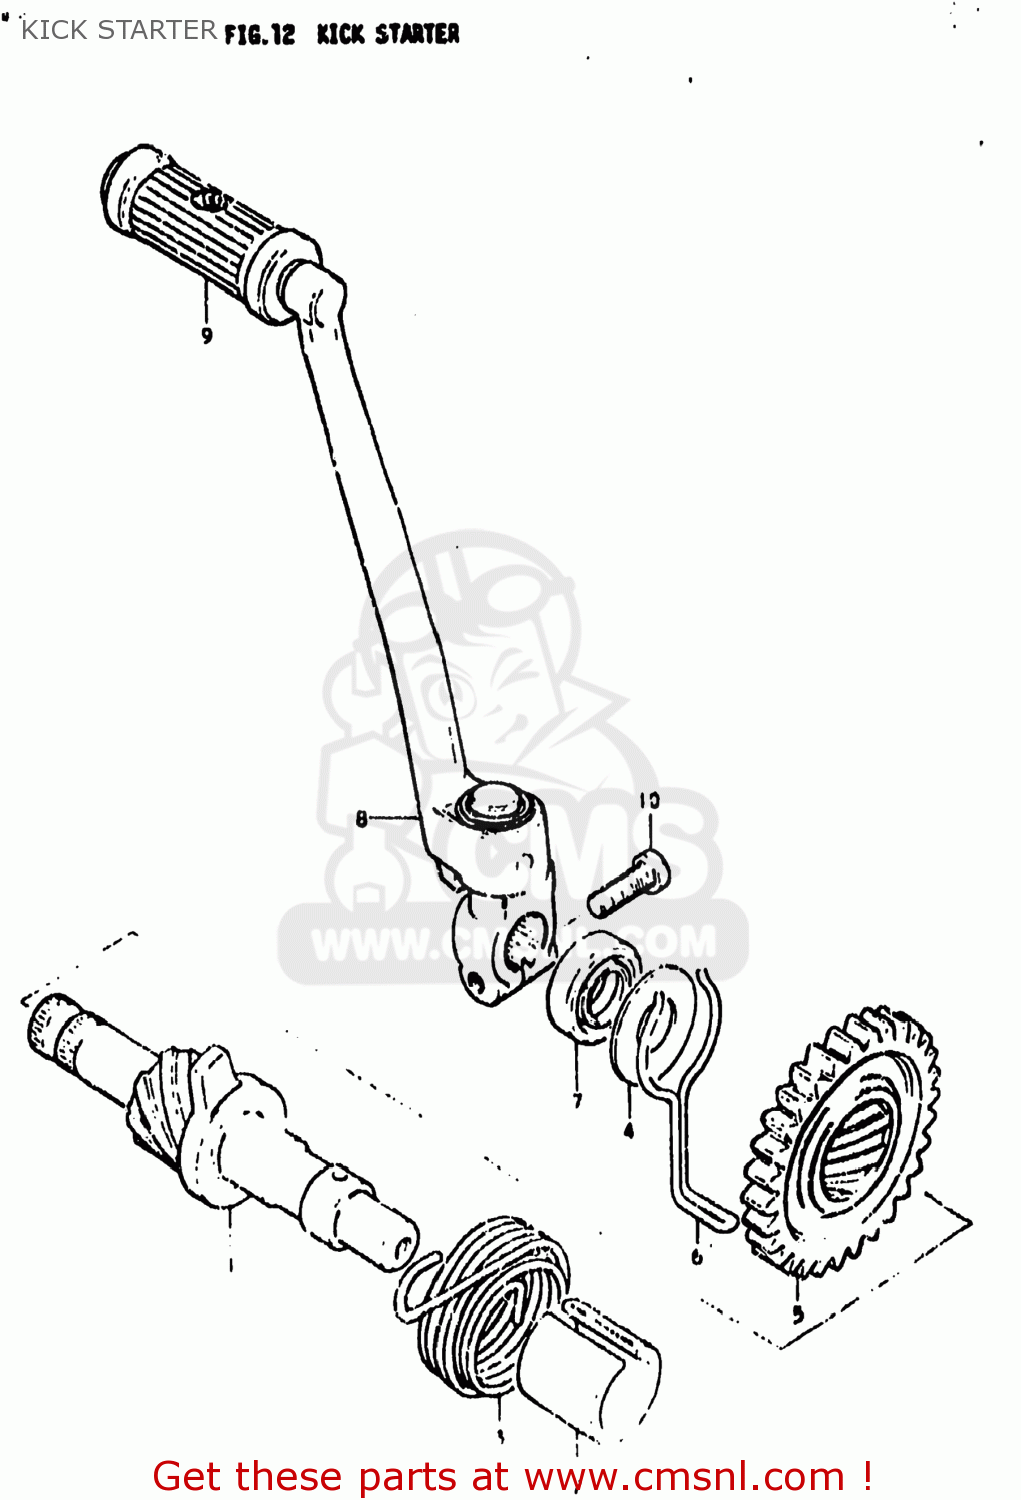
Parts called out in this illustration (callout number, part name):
1	SHAFT,KICK STARTER
2	GUIDE,KICK STARTER SFT SPRING
3	SPRING
4	WASHER
5	GEAR,KICK STARTER DRIVE(NT:30)
6	RETAINER,SNAP
7	SEAL,OIL(14X24X6)
8	LEVER ASSEMBLY,KICK STARTER
9	RUBBER,KICK STARTER PEDAL
10	BOLT
